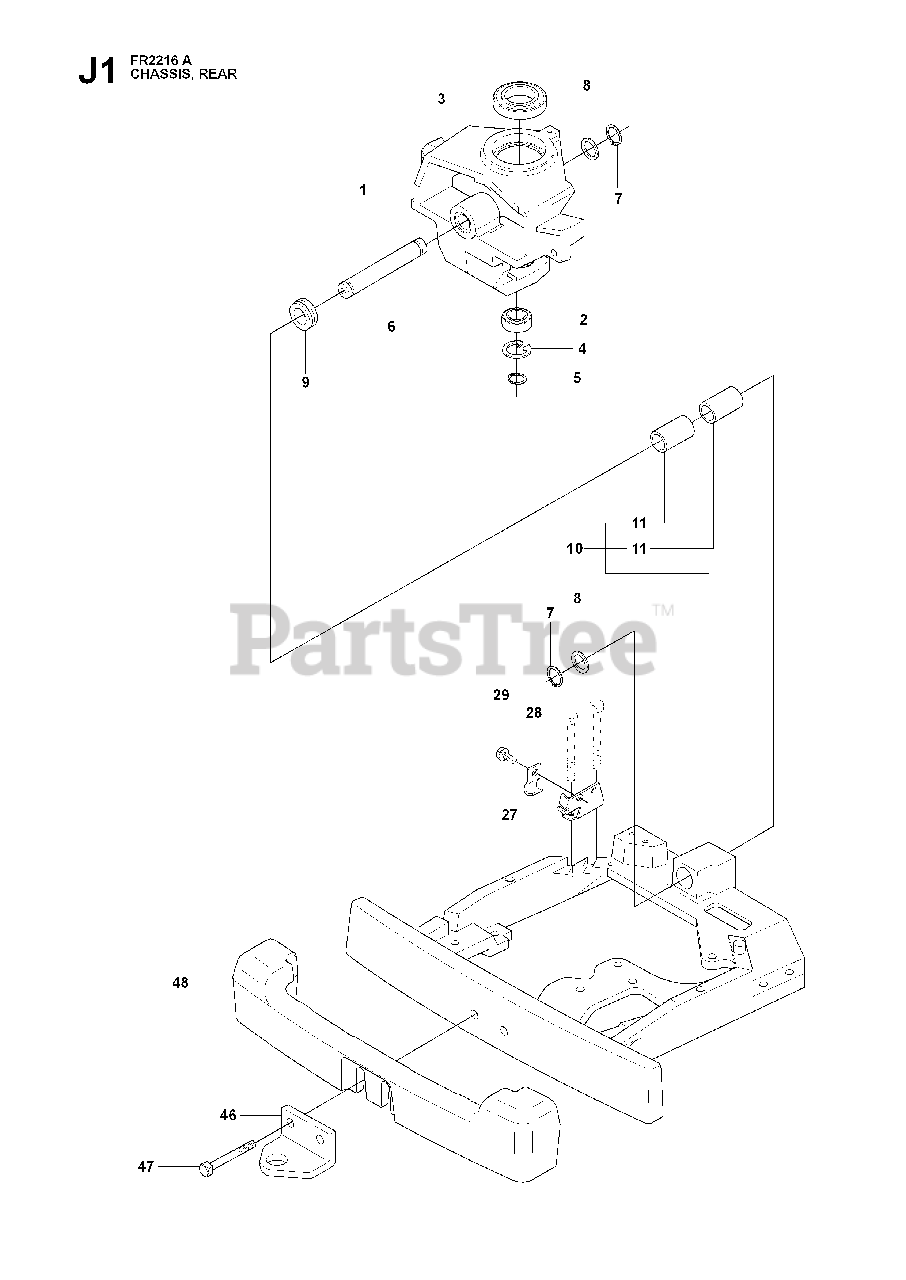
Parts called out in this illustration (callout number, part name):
2	BALL BEARING 6005-2RS
3	BALL BEARING 6010 2RS1
4	CIRCLIP SGH 47
5	RETAINING RING SGA 25
7	RETAINING RING SGA 25
46	DRAW RING
